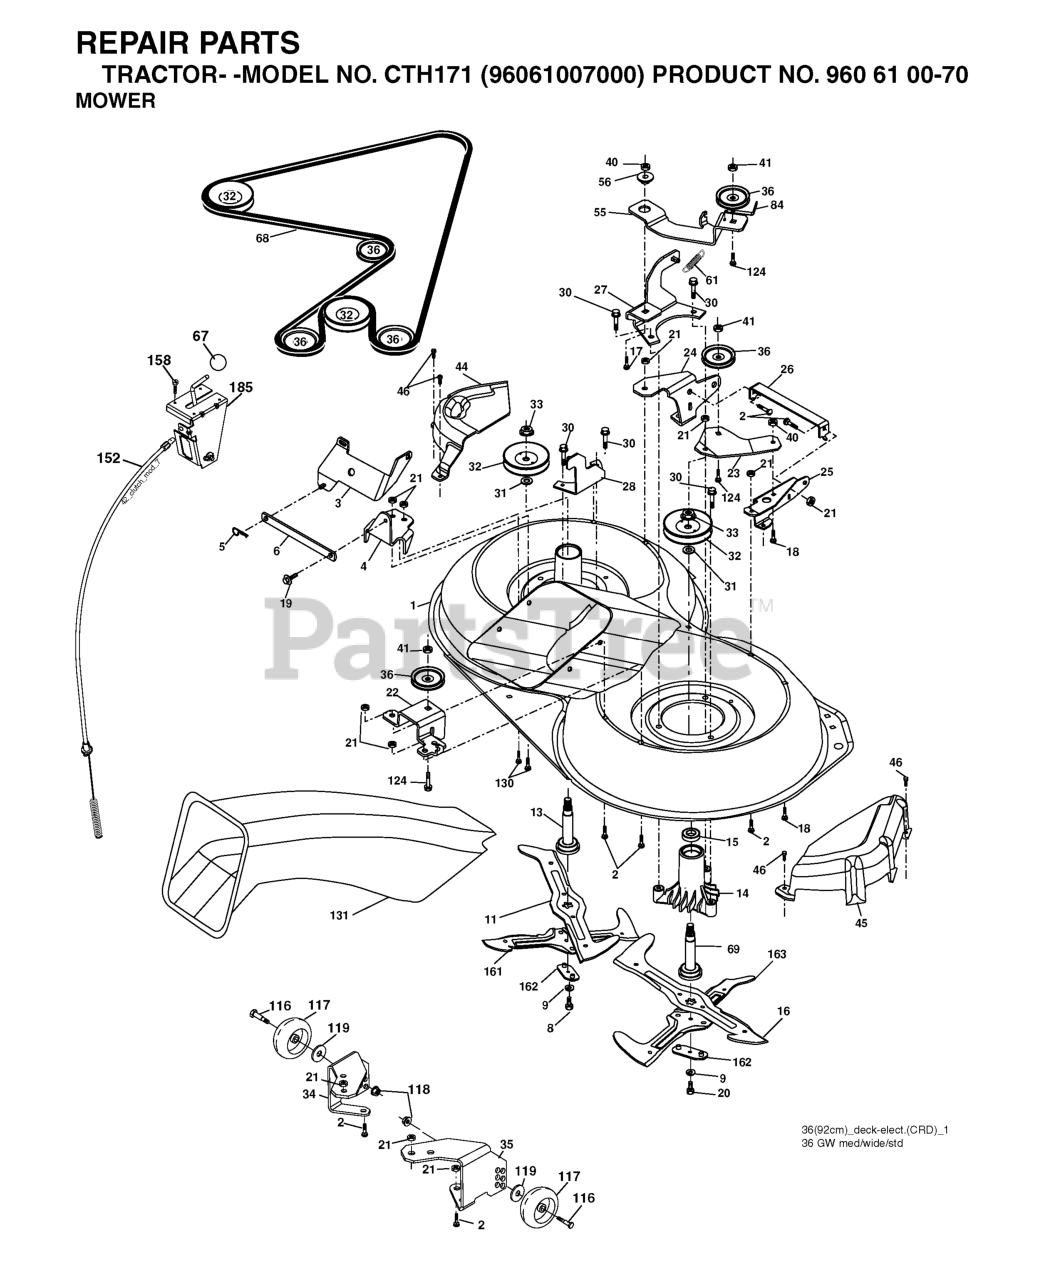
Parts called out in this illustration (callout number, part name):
2	RP BOLT 5/16-18 X3/4 ZN/YEL GR
5	RETAINER-SPRNG RB
6	BAR.SWAY.92.CRD
8	BOLT.3/8-24X1.25 GR8
9	LOCKWASHER
13	SHAFT ASM VENT
14	HOUSING.MANDREL.VENTED (MACHD)
17	BOLT.3/8-14X1.25
19	BOLT SHD 5/16-18
20	BOLT.3/8-24X1.25GR8. LHTHRD
21	LOCKNUT
26	SUPPORT
30	SCREW, WASHER HEAD
31	WASHER.SPACER.MANDREL
33	NUT.FLANGE.LOCK.TOP
36	PULLEY.IDLER.4.25
41	NUT LOCK FLG 3/8-16 UNC
45	COVER.MANDREL.RH.CRD
46	SCREW.1/4-20X5/8
55	ARM.IDLER.92 CRD.2006
56	SPACER.RETAINER.MOWER
61	SPRING
67	KNOB T (3/8 HOLE)
68	BELT.DRIVE.92CM.CRD.2006
69	SHAFT.ASM.W/LWR.BRG.RH.THREAD
84	KEEPER, BELT IDLER
116	SHOULDER BOLT
117	RP WHEEL. GUAGE RALLY
118	LOCKNUT
119	WASHER.5/16.FLAT.STE.STD.
124	BOLT.3/8-16X1.50
130	BOLT.CARR.SQNK.5/16-18UNC.X3/4
131	CHUTE BAGGER
158	SCREW
169	COVER TERMINAL BATTERY
185	HEAD ASM. CABLE CLUTCH
